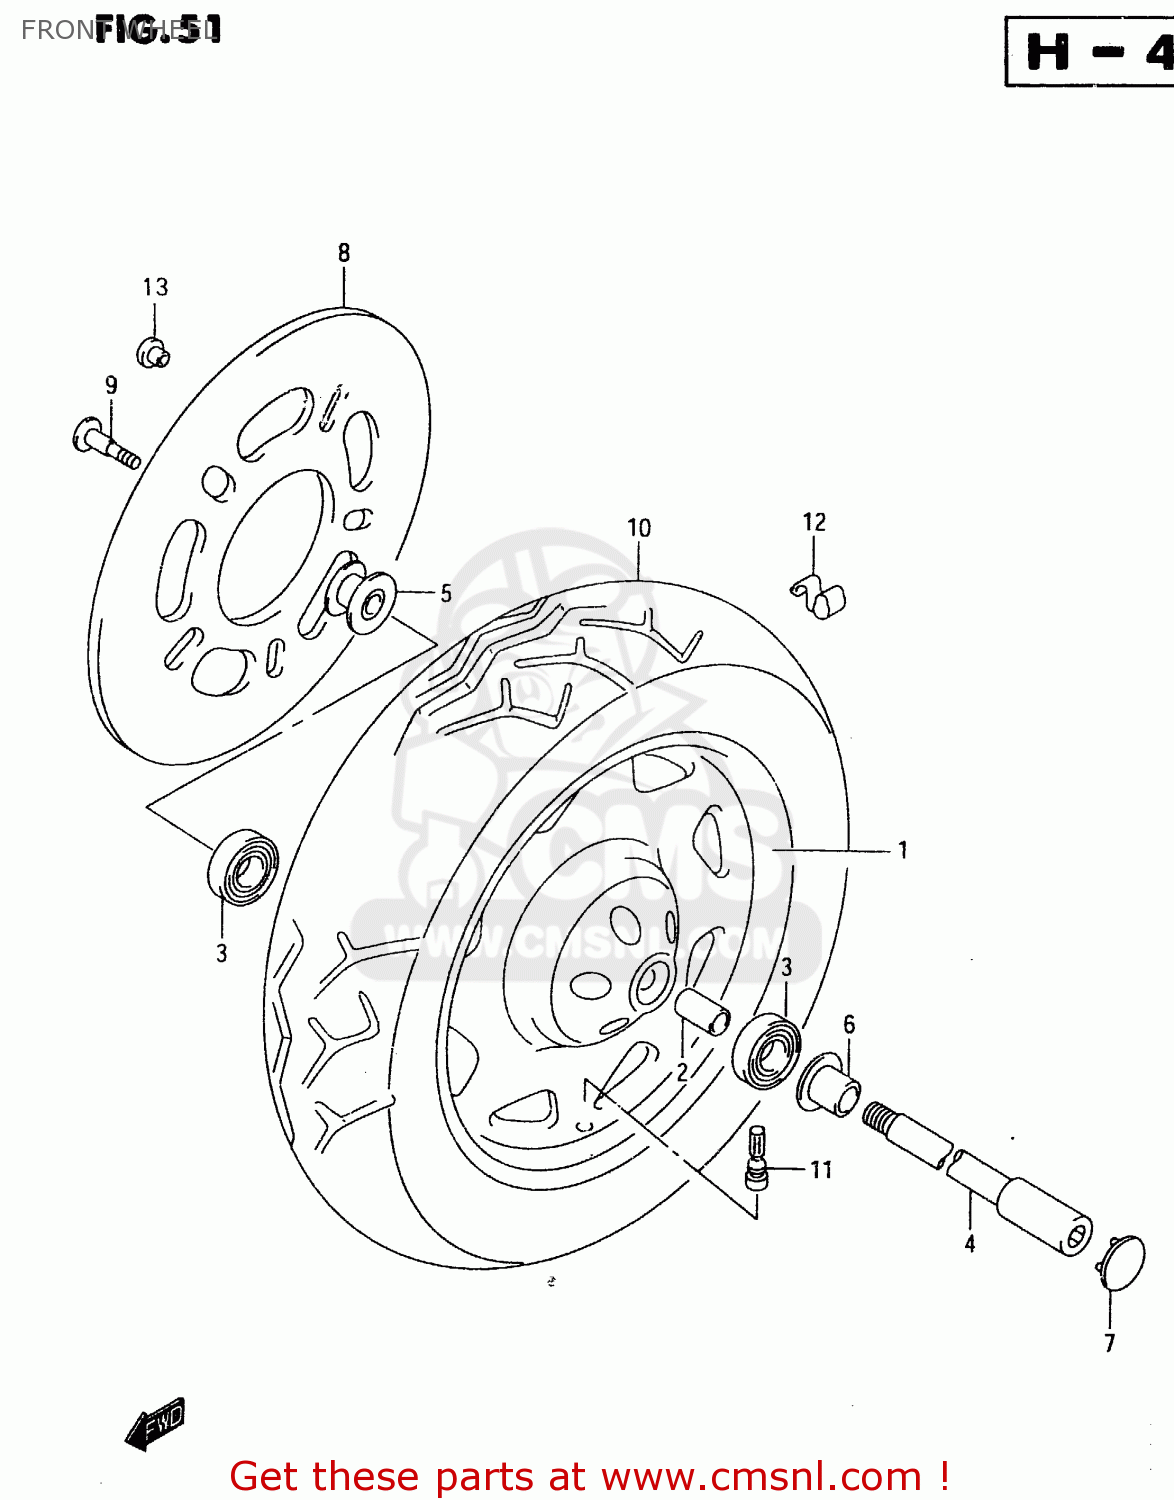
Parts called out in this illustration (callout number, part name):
1	WHEEL,FRONT (16XMT3.50)
2	SPACER,FR HUB BEARING
3	BEARING
4	AXLE,FRONT
5	SPACER,FR AXLE,R
6	SPACER,FR AXLE,R
7	CAP,FR AXLE
8	DISC,FR BRAKE
9	BOLT 8X33
10	TIRE,FRONT 150/80-16.7
11	VALVE ASSEMBLY,WHEEL,TR412
12	WEIGHT,BAL. 30
13	CAP,FR AXLE
